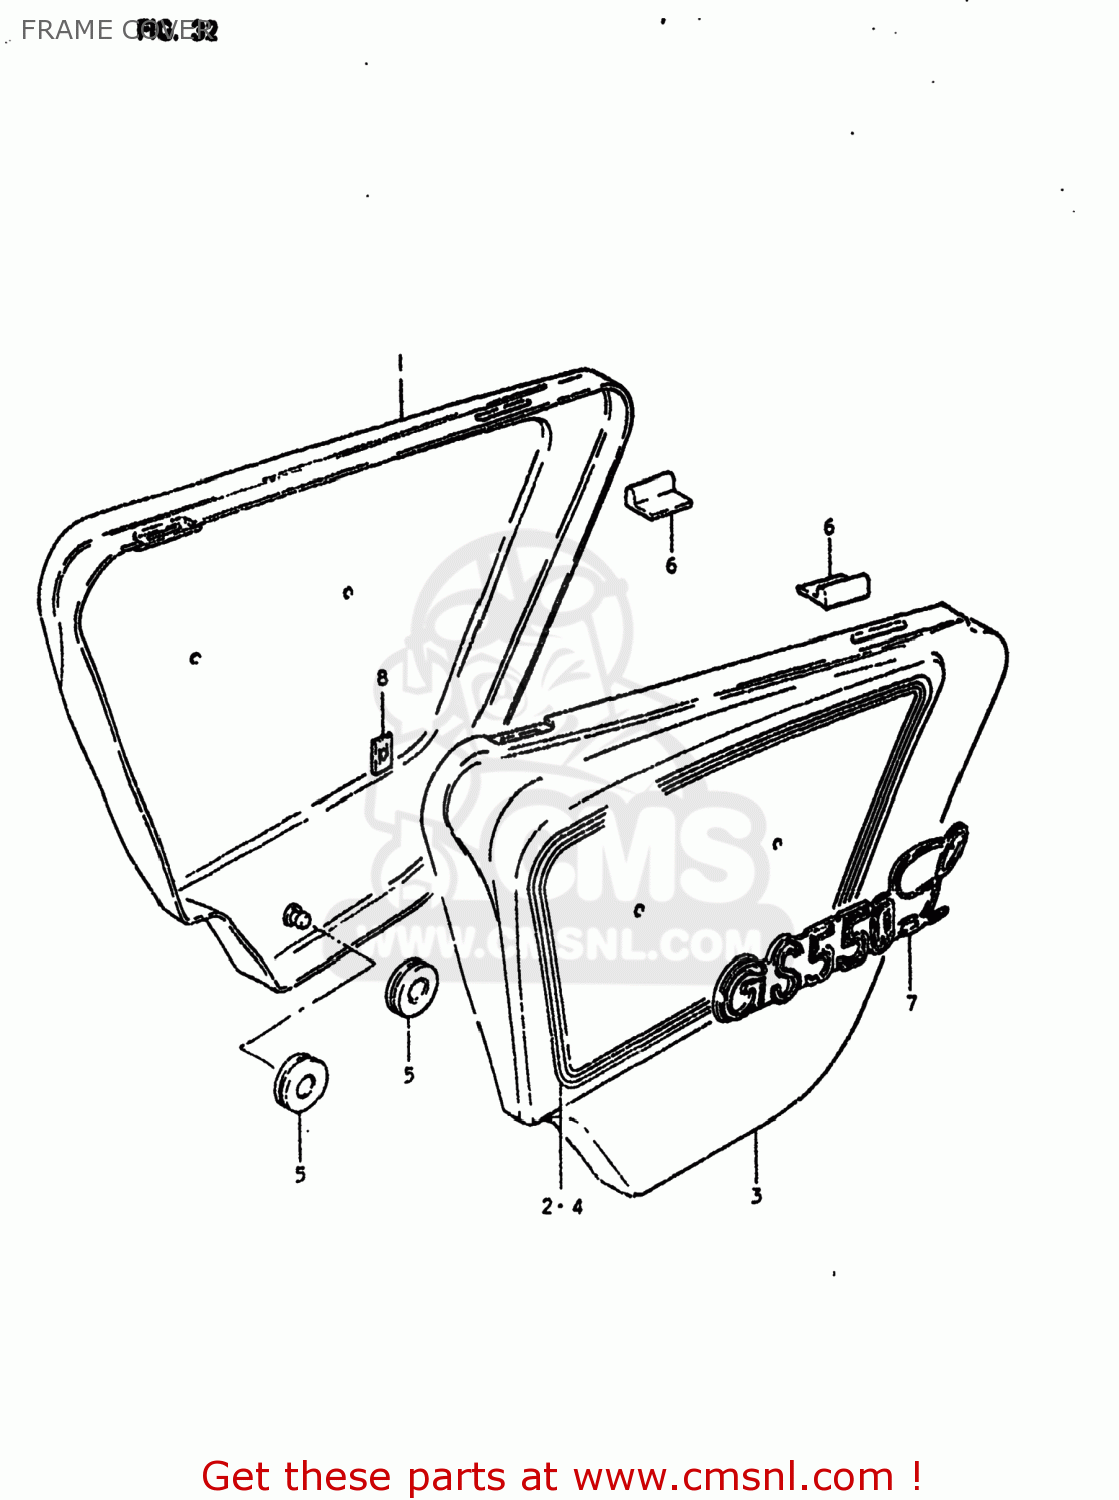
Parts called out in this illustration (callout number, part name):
1	COVER,FRAME,RIGHT
2	TAPE SET,FRAME COVER
3	COVER,FRAME,LEFT
4	TAPE SET,FRAME COVER
5	CUSHION
6	CUSHION,FRAME COVER
7	EMBLEM
8	NUT
